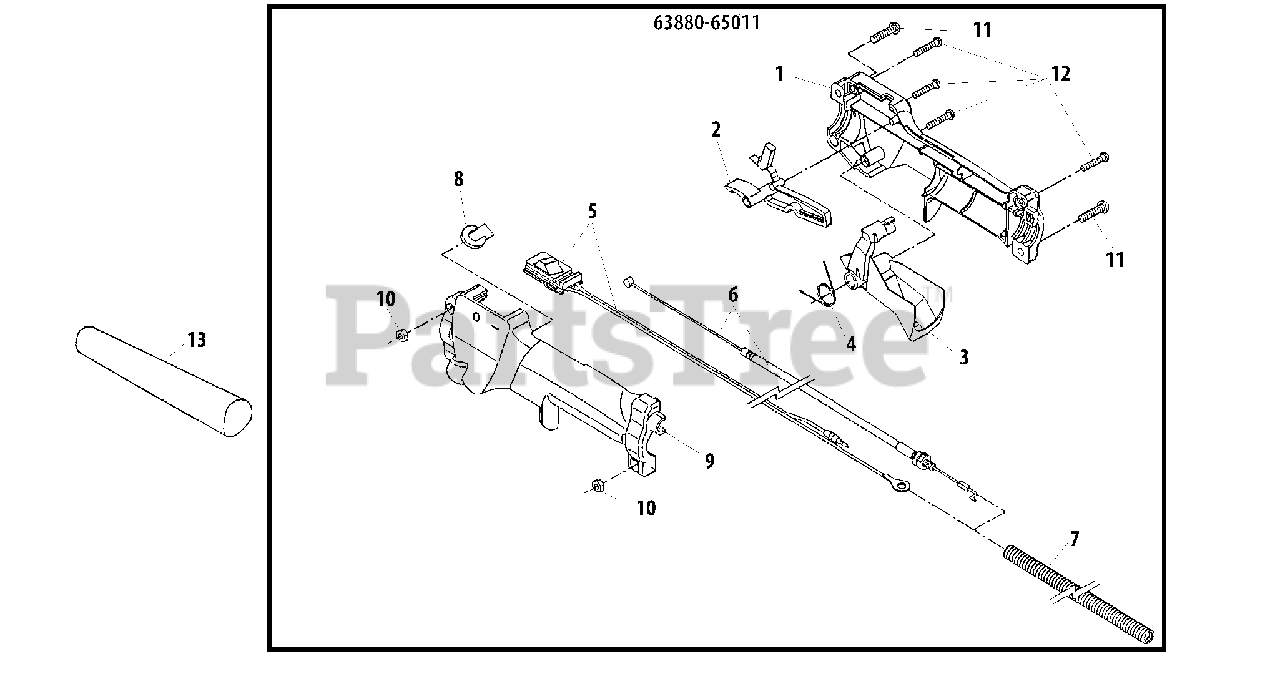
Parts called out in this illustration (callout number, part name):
1	CONTROL HANDLE - RIGHT
2	LEVER, THROTTLE LOCKOUT
3	TRIGGER, THROTTLE
4	SPRING, THROTTLE RETURN
5	SWITCH, ON-OFF
6	CABLE, THROTTLE
7	TUBE, PLASTIC PROTECTIVE
8	PLUG
9	CONTROL HANDLE - LEFT
10	NUT M5
11	SCREW M5×20
12	SCREW, TAPPING M4×20
13	COLLAR
63880-65011	THROTTLE CONTROL ASSY
